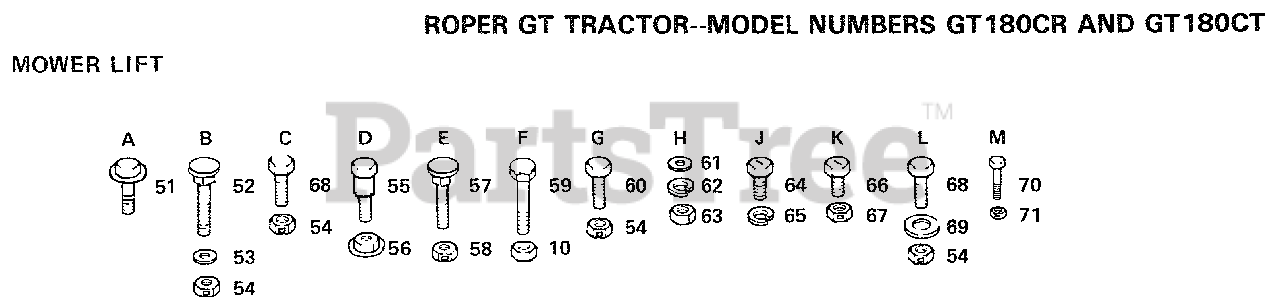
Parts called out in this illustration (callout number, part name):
51	SCREW LT
52	BOLT
53	WASHER
55	SHOULDER BOLT T
56	NUT T
57	BOLT
58	LOCKNUT
59	BOLT
61	WASHER PM
68	BOLT
69	WASHER M
70	BOLT
